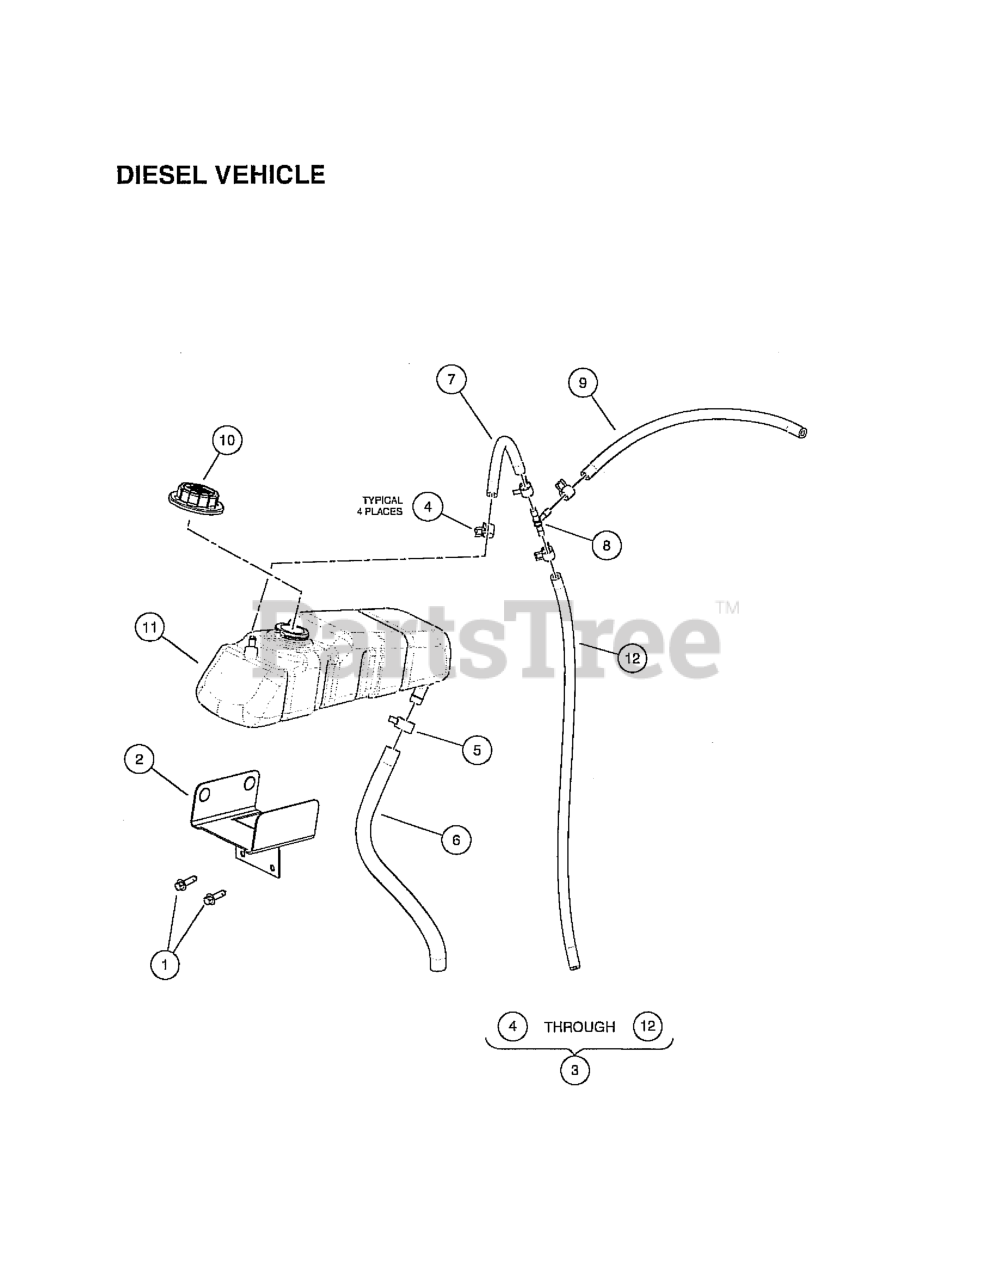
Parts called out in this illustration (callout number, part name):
1	SCREW-M8 X 1.25 30, TRI, HX F
2	BRACKET, COOLANT BOTTLE
4	CLAMP, HOSE, CTB 15MM
5	CLAMP, HOSE, CTB 22MM
6	HOSE, COOLANT FILL
7	HOSE, COOLANT TEE TO BOTTLE
8	FITTING, TEE
9	HOSE, COOLANT RAD TO TEE
10	CAP, PRESSURE 14 PSI
11	TANK, EXPANSION
12	HOSE, TEE TO VENT TUBE, COOLNT
